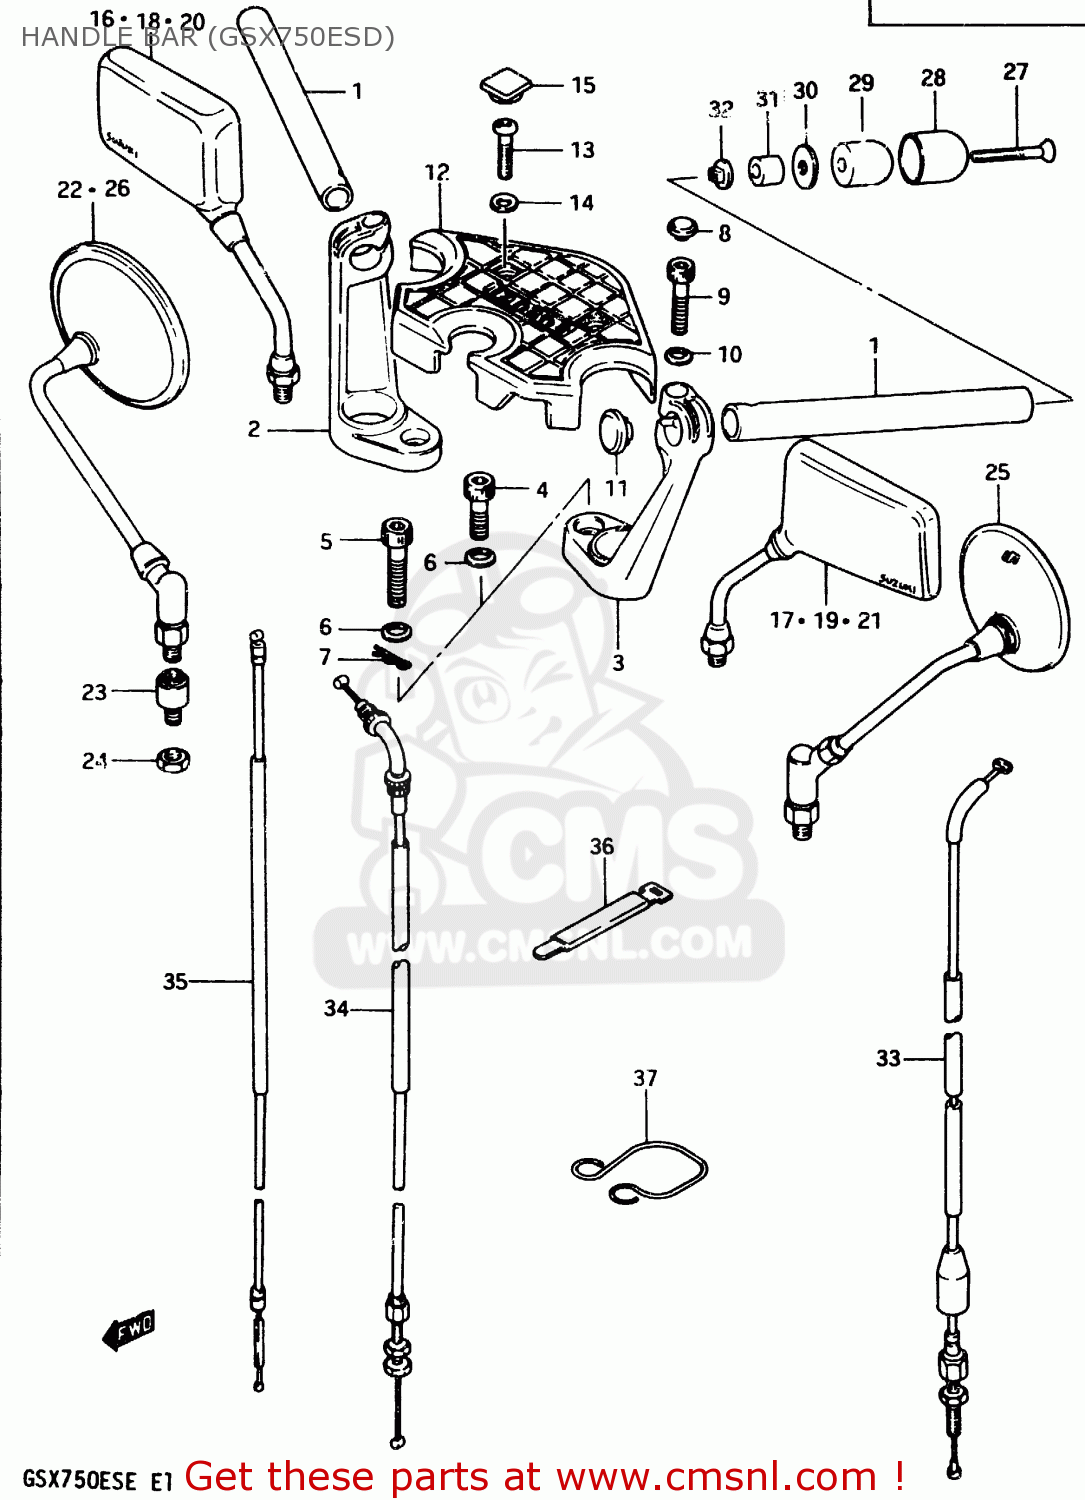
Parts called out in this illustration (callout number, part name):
1	HANDLEBAR
2	HOLDER,HANDLEBAR,RIGHT
3	HOLDER,HANDLEBAR,LEFT
4	BOLT
5	BOLT 10X50
6	WASHER
7	CLIP
8	CAP(OD:14.5)
9	BOLT 8X35
10	WASHER
11	CAP,GRIP END
12	PAD,HANDLE
13	SCREW
14	WASHER
15	PLUG
16	MIRROR ASSEMBLY,RIGHT
17	MIRROR ASSEMBLY,REAR VIEW
18	MIRROR, REAR VIEW RH
19	MIRROR, REAR VIEW LH
20	MIRROR, REAR VIEW RH
21	MIRROR, REAR VIEW LH
22	MIRROR ASSY,RR VIEW
23	CUSHION,REAR VIEW MIRROR
24	NUT
25	MIRROR ASSY,RH
26	MIRROR, REAR VIEW
27	SCREW 6X65
28	CAP,BALANCER
29	BALANCER,HANDLE
30	SPACER,BALANCER
31	EXPANDER,BALANCER
32	NUT
33	CABLE ASSY,CLUTCH
34	CABLE ASSY,THROTTLE
35	CABLE COMP,STARTER
36	CLAMP
37	GUIDE,CABLE/HARNESS
